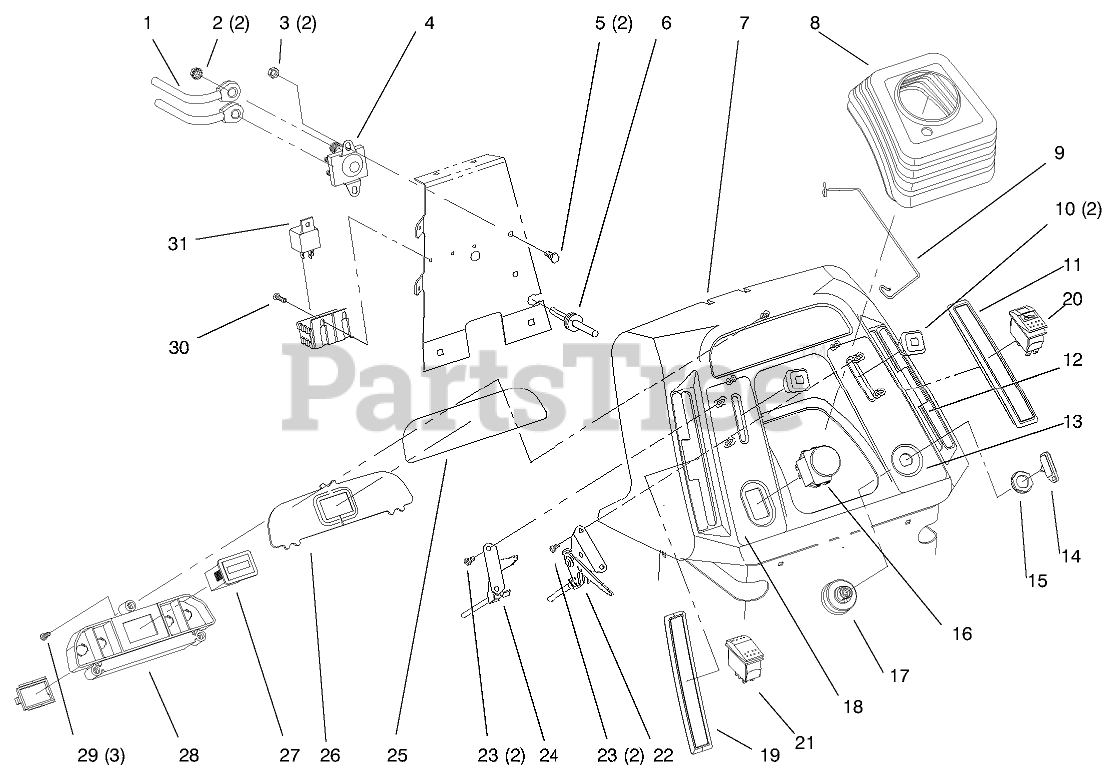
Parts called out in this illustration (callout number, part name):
1	WIRE-21 INCH
2	NUT-KEPS
3	NUT-LOCK, NI
4	Solenoid
5	SCREW-HH
6	GROMMET-RUBBER
8	BOOT-STEERING
9	CLIP-BOOT
11	COVER-SLOT, RH
13	Decal-Throttle/Ignition (Only On: 72046)
13	Decal-Dash (Only On: 72064)
14	KEY-IGNITION
16	SWITCH-PTO
17	SWITCH-IGNITION
18	Decal-Choke/PTO (Only On: 72046)
18	Decal-Dash (Only On: 72064)
19	COVER-SLOT, LH
22	CONTROL-THROTTLE
24	CONTROL-CHOKE
25	Decal-Dash Lens (Only On: 72064)
25	Decal-Dash Lens (Only On: 72046)
26	LENS-DASH
27	HOURMETER
28	Light-Indicator (Only On: 72046)
28	Housing-Indicator Light (Only On: 72064)
29	SCREW
30	SCREW-PPHTF
31	RELAY
